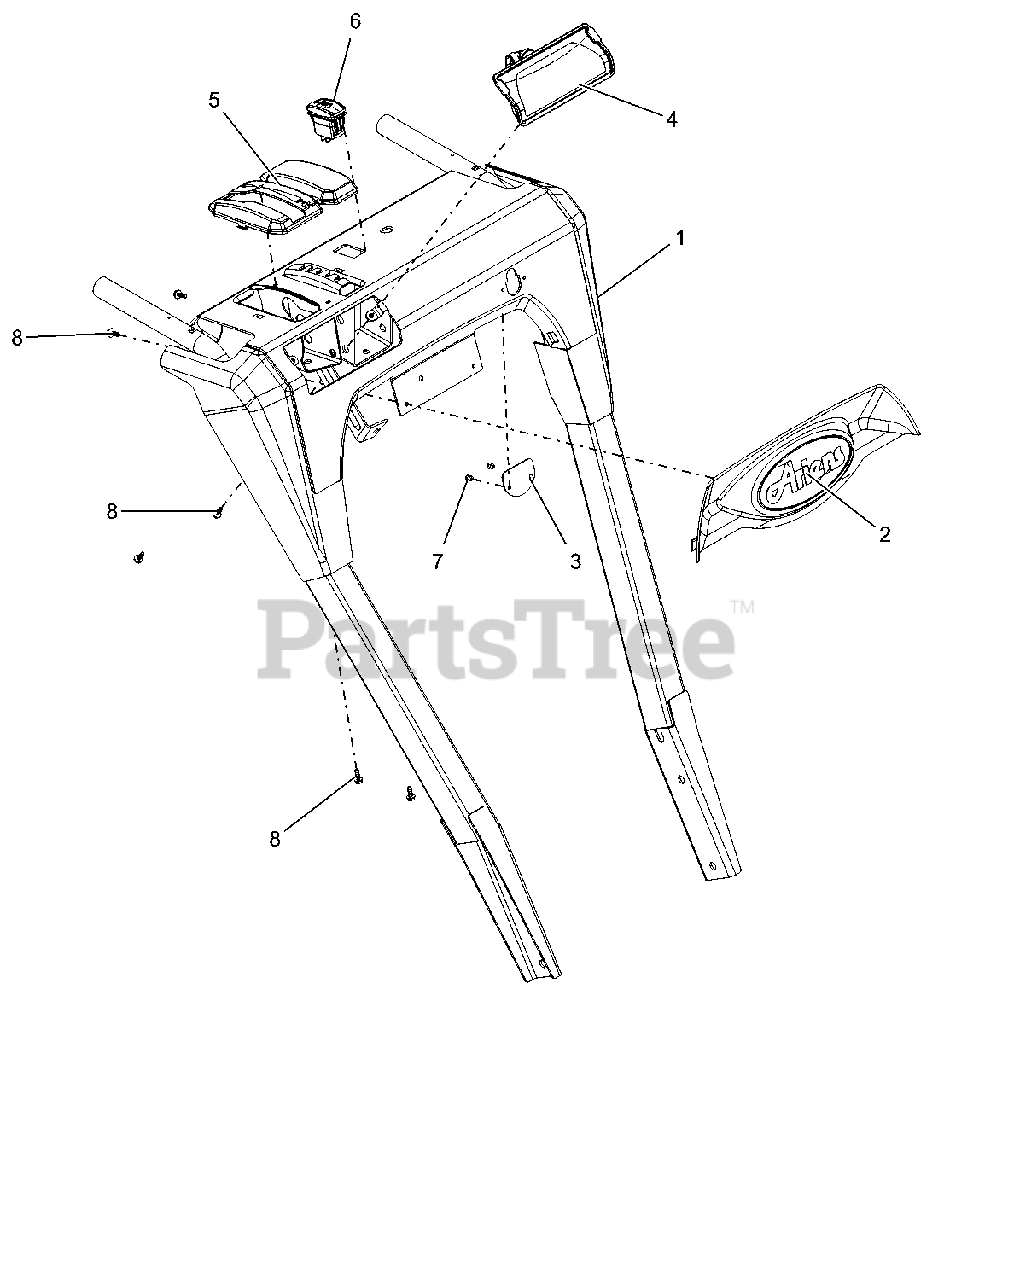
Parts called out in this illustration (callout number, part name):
1	PANEL, DASH - W/CTR DECAL(12V)
2	BEZEL, DASH-ARIENS LG DASH
3	COVER, DASH BRKT, BRUSH
4	HEADLIGHT ASY, HOLO 15W 2 SHOT
5	BEZEL, SHIFT - HYDRO BRUSH
6	SWITCH,ROCKER SPST-ON/OFF
7	RVT-POP #43 .125X.313 STL ZINC
8	SCR-TAP #10X.50 BOSS INDHXHD
